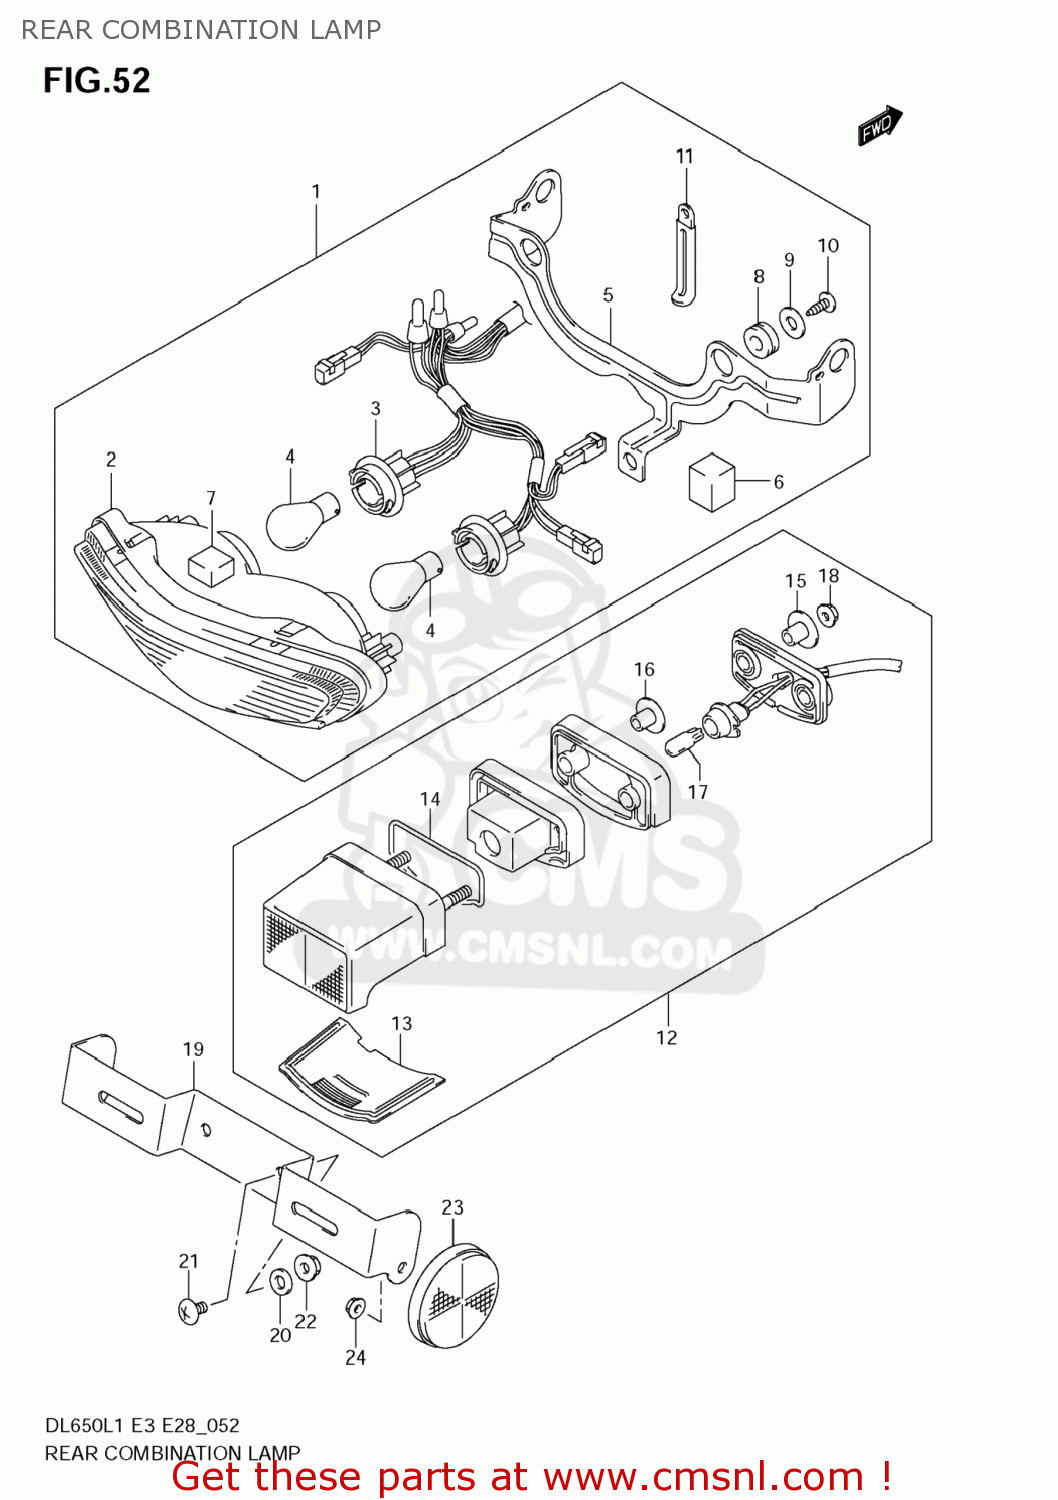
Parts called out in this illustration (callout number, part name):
1	LAMP ASSY,RR COMBINATION
2	UNIT
3	SOCKET & CORD
4	BULB(12V21/5W)
5	BRACKET
6	CUSHION
7	CUSHION
8	CUSHION
9	WASHER(5.5X20X1.2)
10	SCREW
11	CLAMP(L:45)
12	LAMP ASSY,LICENSE
13	LENS
14	GASKET (NAS)
15	SPACER
16	SPACER
17	BULB(12V5W)
18	NUT
19	BRACKET,LICENSE PLATE
20	WASHER(6.5X15X1.6)
21	SCREW
22	NUT
23	REFLECTOR ASSY,RR SIDE
24	NUT
